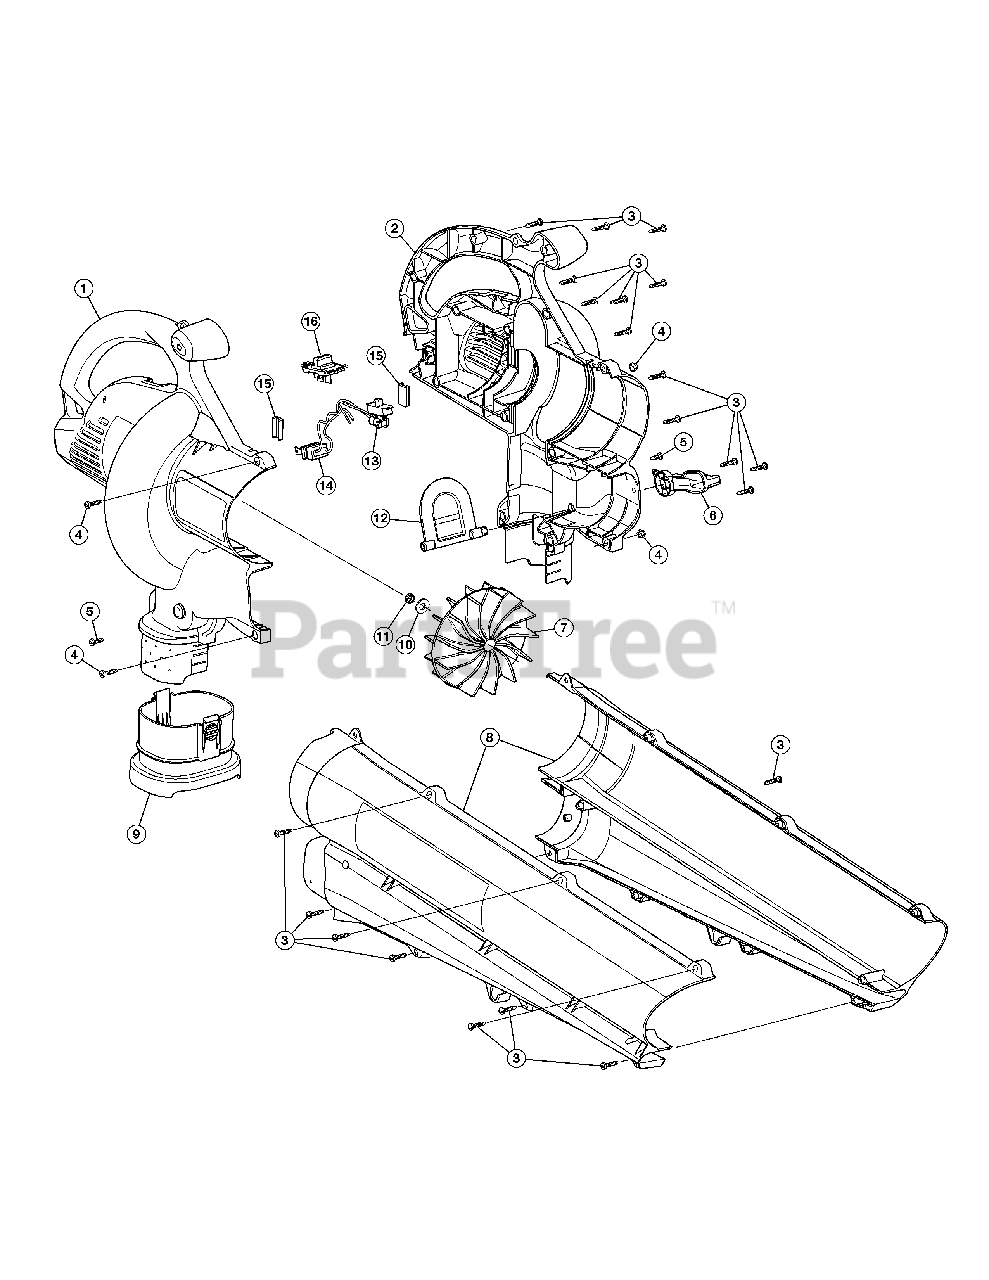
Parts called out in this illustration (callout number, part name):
1	Left Motor Housing
2	Right Motor Housing
3	Housing Screw
4	Blower/ Vac Tube Mounting Hardware
6	Mode Control Lever
7	Impeller
8	Blower/ Vac Tube Assembly (Incl. 3)
9	Vacuum Bag Assembly
12	Mode Control Flapper
13	Switch Assembly
14	Power Connection Wire Assembly
15	Rubber Cushion
16	Switch Lever
